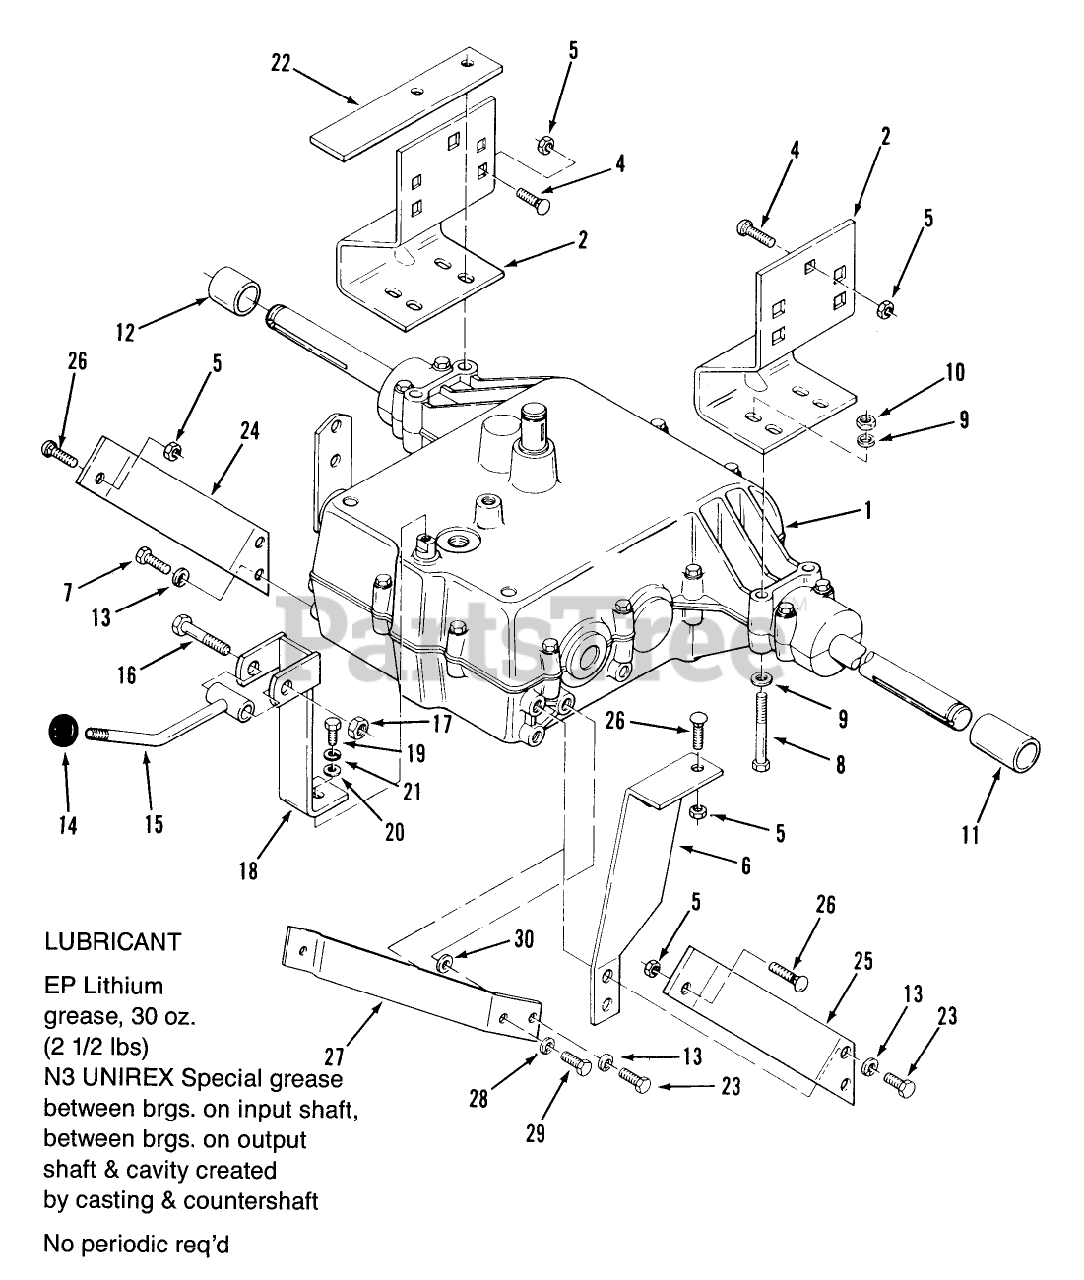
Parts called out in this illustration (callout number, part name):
1	ORDER FROM PEERLESS
1	Transmission-4-Speed Peerless Model 900
4	CARRIAGE BOLT -4
6	TORQUE STRAP
6	STRAP-TORQUE *R
7	Screw
9	WASHER 5/16 SAE
15	ASSY-UPPER SHIFT ROD
18	ASSY-LEVER LOWER SHT
20	WASHER
29	Bolt, 1/4-20 x 3/4 Swage Form
